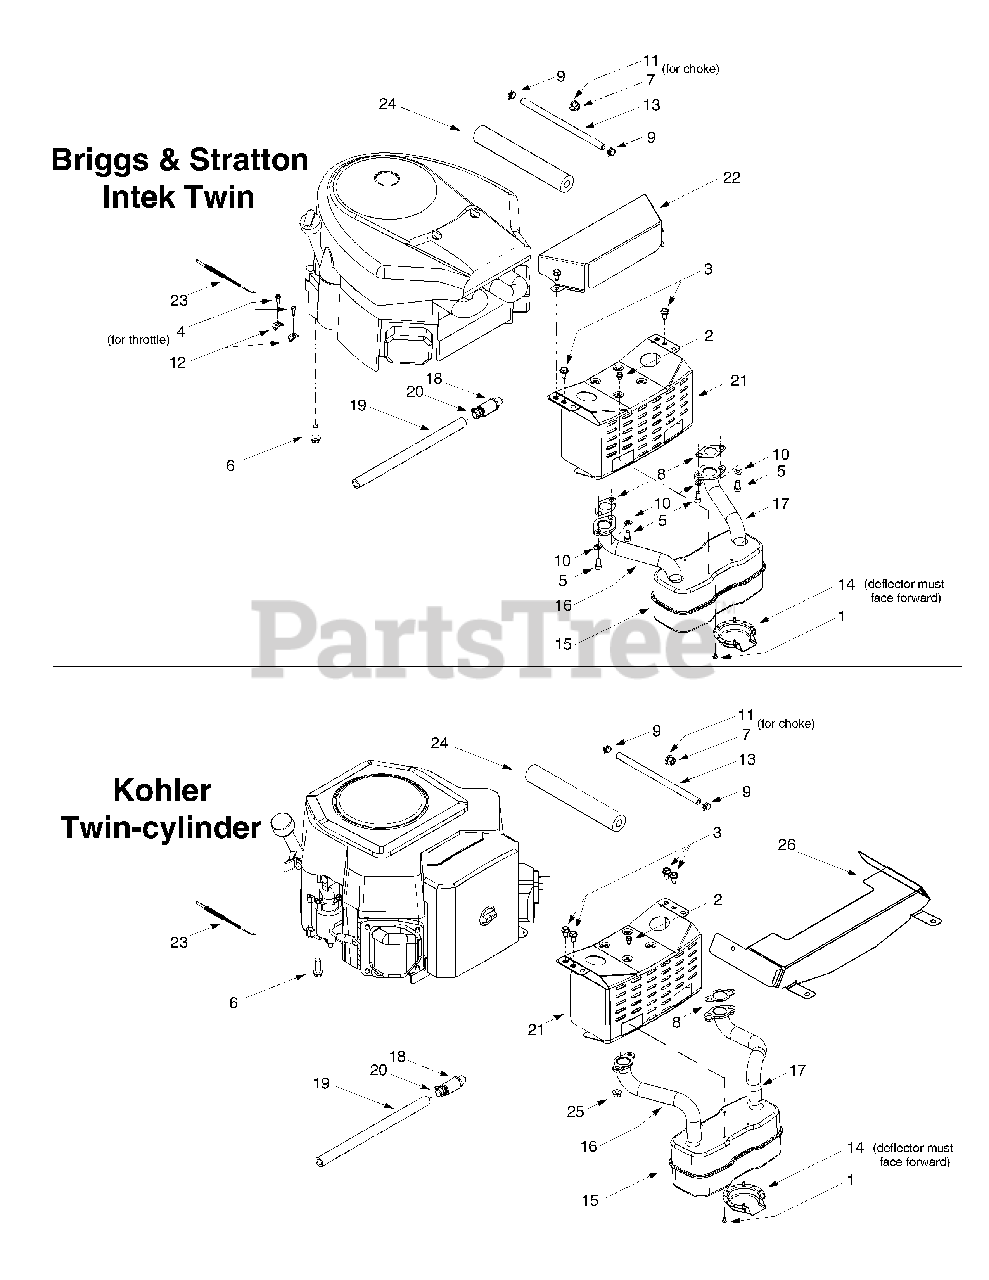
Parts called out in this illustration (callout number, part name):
1	Self Tapping Screw, #8-32 x .375
2	Self Tapping Screw, 1/4-20 x .5
3	Self Tapping Screw, 5/16-18 x .625
4	Screw, #10-32 x .625
5	Socket Cap Screw, 5/16-18 x .625
6	Self Tapping Screw, 3/8-16 x 1.25
7	Hex Nut, 3/8-16
8	Exhaust Gasket (Intek Twin)
8	Exhaust Gasket (Kohler Twin)
9	Hose Clamp
10	Lock Washer, 5/16
11	Flat Washer, .406 x .875 x .059
12	Casing Clamp
13	Fuel Line Hose
14	Muffler Deflector
15	Muffler (Intek Twin)
15	Muffler (Kohler Twin)
16	RH Exhaust Pipe (Intek Twin)
16	RH Exhaust Pipe (Kohler Twin)
17	LH Exhaust Pipe (Intek Twin)
17	LH Exhaust Pipe (Kohler Twin)
18	Oil Drain Valve
19	Oil Drain Hose
20	Oil Drain Cap
22	Engine Heat Shield (Intek Twin)
23	Throttle Cable (Intek Twin & Kohler Twin)
24	Foam (fits over fuel line)
25	Flange Nut, M8 x 1.25-6
26	Heat Shield (Kohler Twin) (Mounts to Grille Front)
